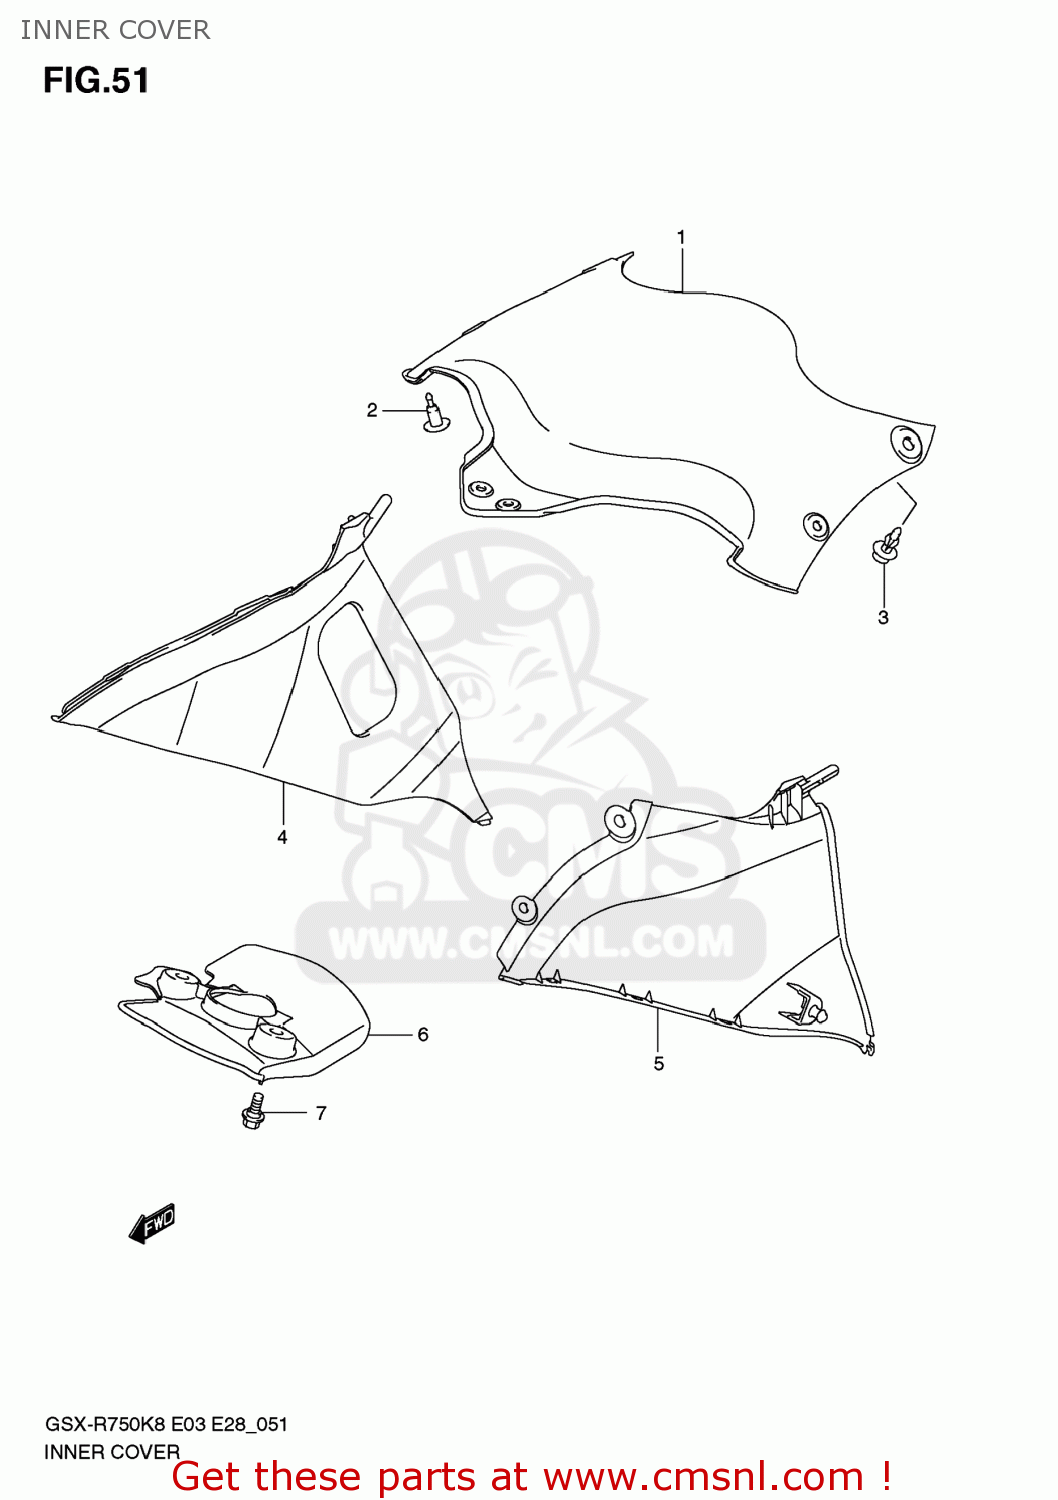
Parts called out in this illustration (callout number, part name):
1	COVER,BODY COWLING
2	CLIP(BLACK)
3	CLIP(BLACK)
4	COWLING,UNDER INNER,R
5	COWLING,UNDER INNER,L
6	COVER,LWR BRACKET
7	BOLT
